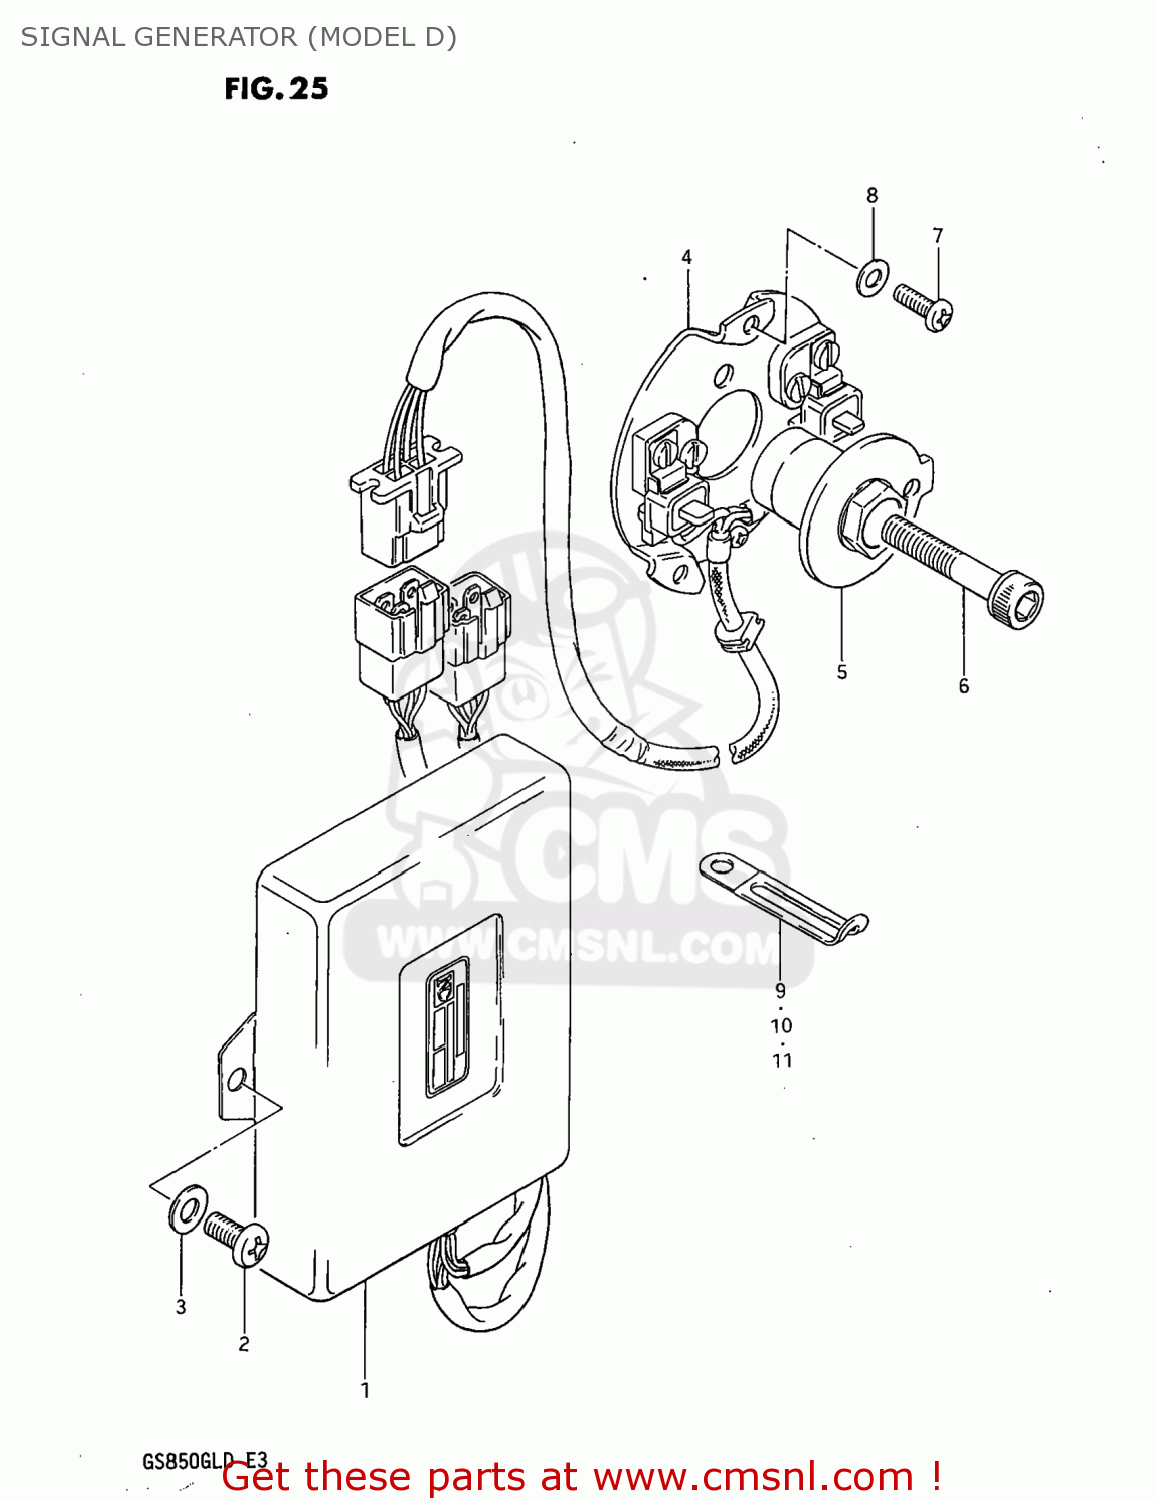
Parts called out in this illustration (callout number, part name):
1	IGNITER UNIT ASSEMBLY
2	SCREW 6X12
3	WASHER
4	STATOR,SIGNAL GENERATOR
5	GOVERNOR ASSEMBLY
6	BOLT
7	SCREW(5X12)
8	WASHER
9	CLAMP L:35
10	CLAMP
11	CLAMP
